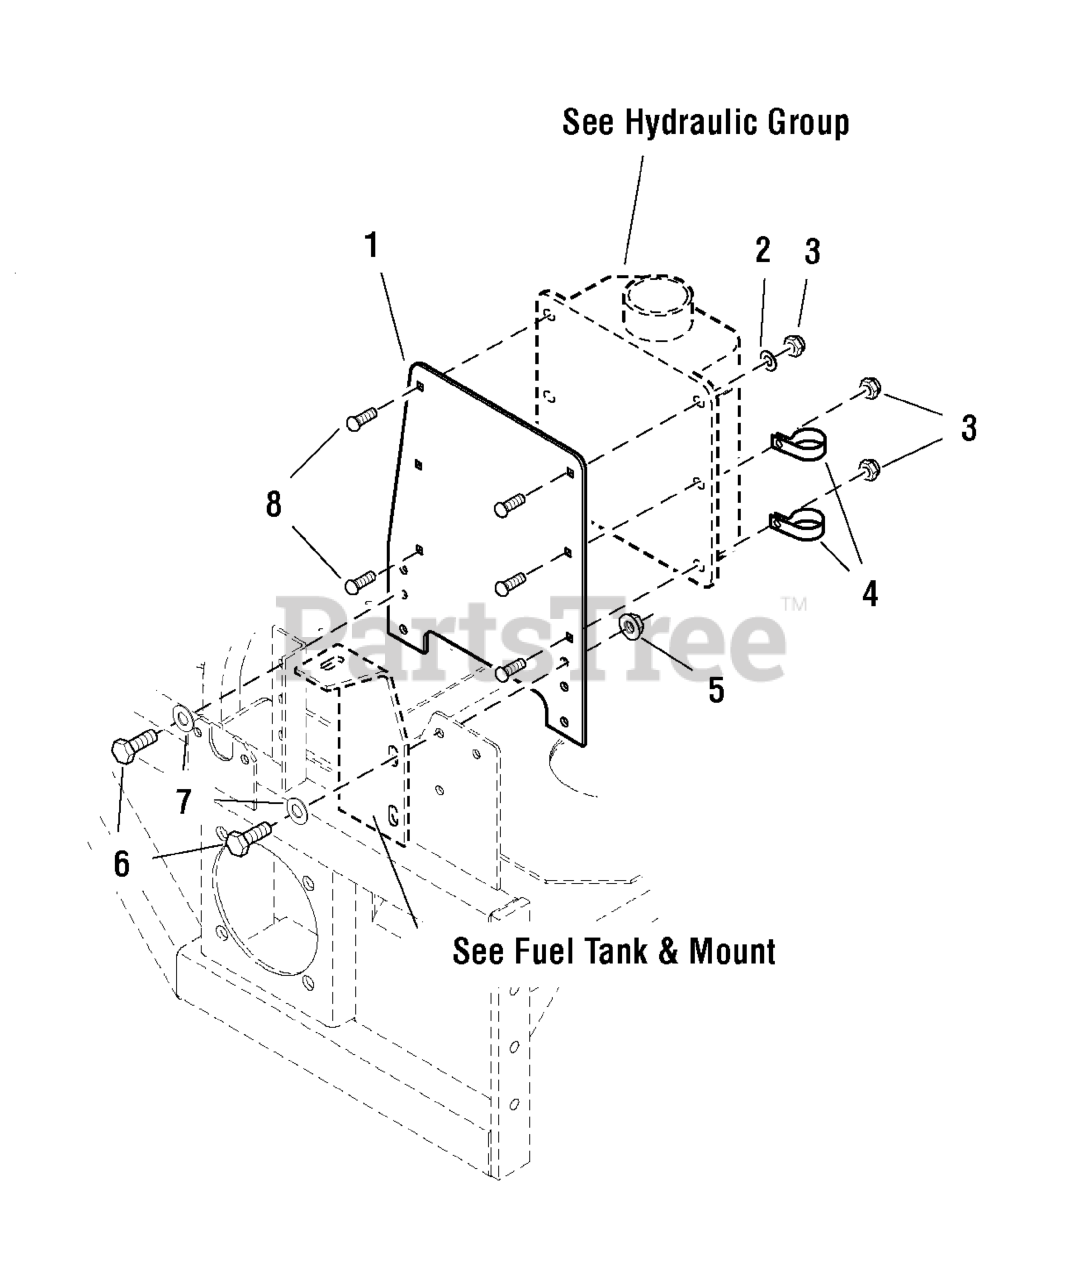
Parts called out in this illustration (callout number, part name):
1	PLATE, Tank Mount
2	WASHER, 1/4 SAE
3	NUT, 1/4-20 HEX NYLON LOCK
4	CLAMP, Vinyl
5	NUT, 5/16-18 HEX SERRATED FLANGE (SMALL)
6	BOLT, 5/16-18 X 1 GD5 YZ
7	WASHER, 5/16" SAE
8	BOLT,1/4-20X0.750,GR5,STD NECK,SQ,ZC/CL
